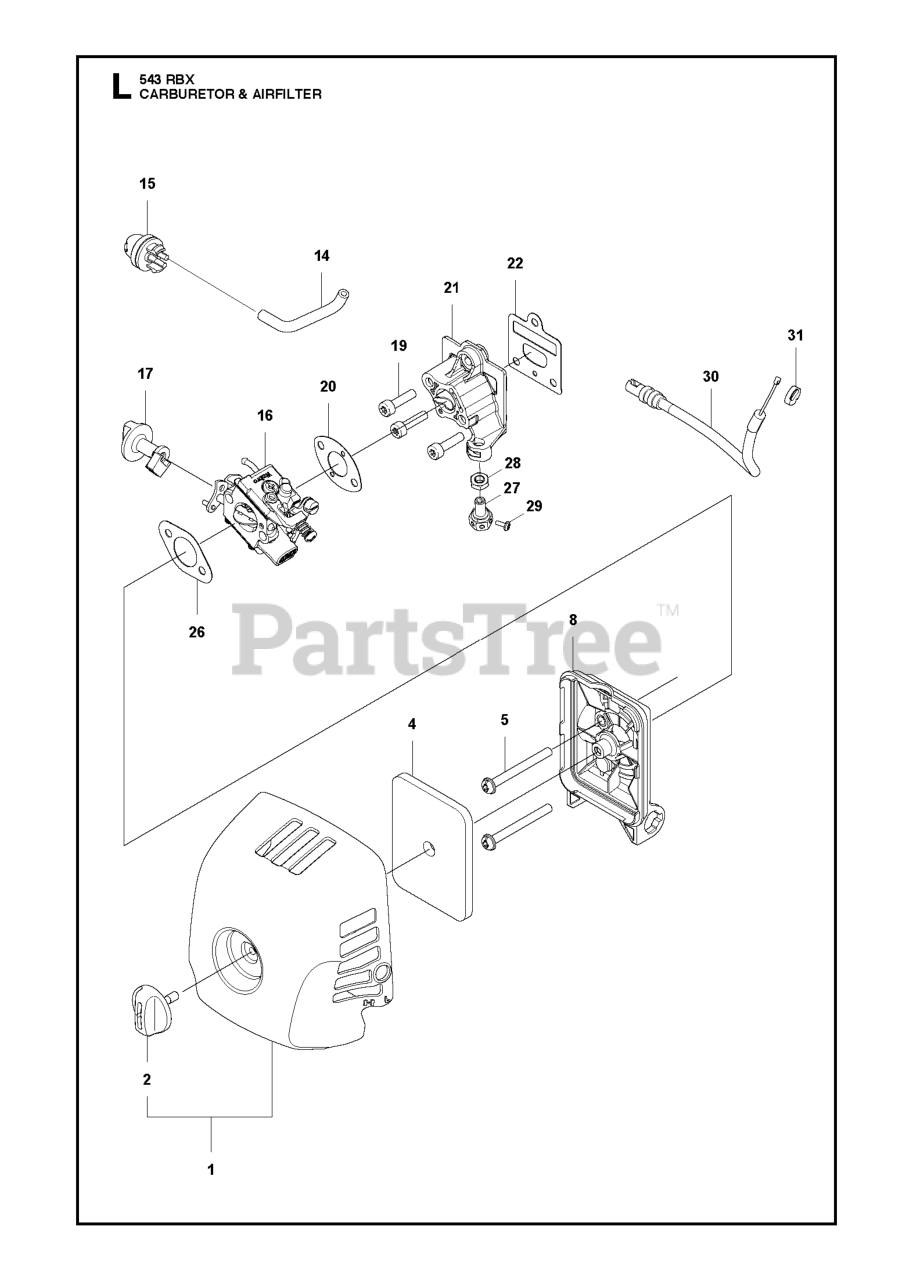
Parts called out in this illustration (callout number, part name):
2	TURNING KNOB GZ40N7
15	PRIMARY BTN
16	CARBURETOR ASSY WTEA-7B
22	GASKET
